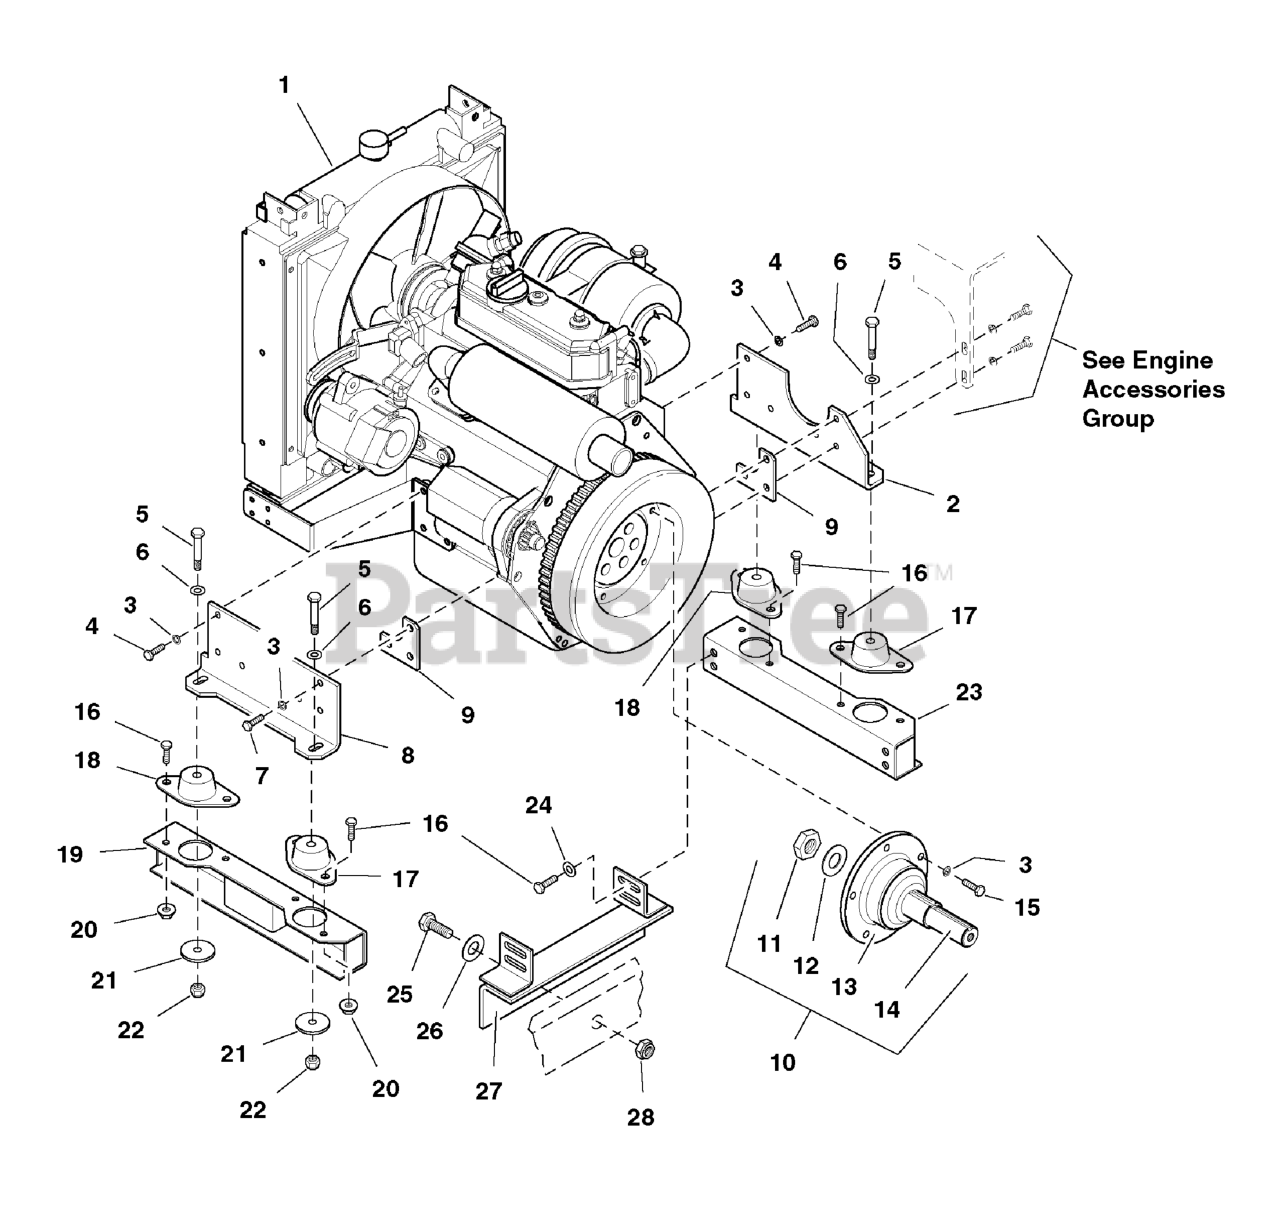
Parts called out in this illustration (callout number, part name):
1	ENGINE, Briggs & Stratton, Gas (Model 950 G)
2	ENGINE MOUNT-RH
3	WASHER, 5/16 LOCK CZ
4	BOLT, M8 x 30MM
5	BOLT, 3/8-16 X 2-1/2" GD5 CZ
6	WASHER, 3/8 SAE
7	BOLT, M8-1.25 X 25MM GR 8.8
8	ENGINE MOUNT-LH
9	SPACER, Engine Mount
10	HUB & SHAFT ASSEMBLY, Complete
11	NUT, 3/4-16 Hex Jam
12	WASHER, 3/4 SAE
13	HUB
14	STUB SHAFT
15	BOLT, M8 x 20MM
16	BOLT, 5/16-18 X 1 GD5 YZ
17	ENGINE MOUNT, Rubber, #150
17	ENGINE MOUNT, Rubber, #215
18	ENGINE MOUNT, Rubber, #50
18	ENGINE MOUNT, Rubber, #150
19	ENGINE MOUNT RAIL-LH
20	NUT, 5/16-18 HEX SERRATED FLANGE (SMALL)
21	WASHER, Iso Mount
22	NUT, 3/8-16 HEX NYLON LOCK
23	ENGINE MOUNT RAIL-RH
24	WASHER, 5/16" SAE
25	BOLT, 1/2-20 X 1-1/2, GD5 CZ
26	WASHER, 1/2 SAE
27	MOUNT, Engine
28	NUT, Hex, Nylon Lock, 1/2-20
